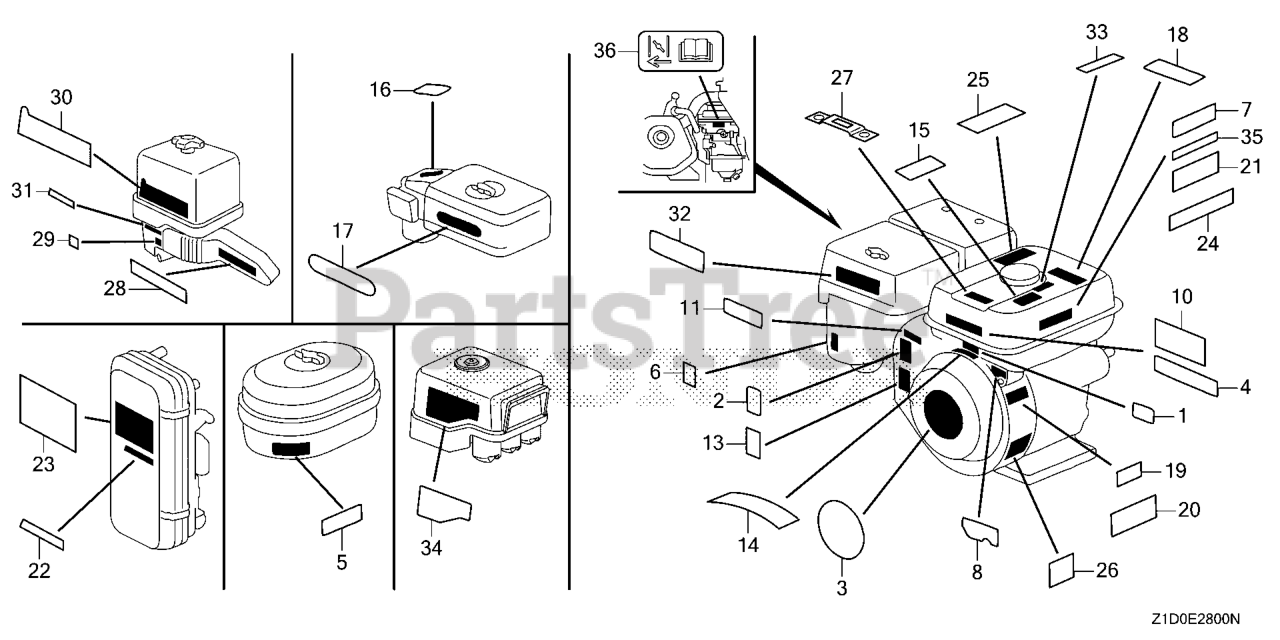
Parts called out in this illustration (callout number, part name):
3	EMBLEM (GX270)
6	MARK, CHOKE
13	LABEL, WARNING (NOT CERTIFIED FOR SALE)
21	MARK, OPERATOR CAUTION (ENGLISH)(MADE IN THAI)
25	MARK, EX. CAUTION (ENGLISH)
32	MARK, SALES POINT
